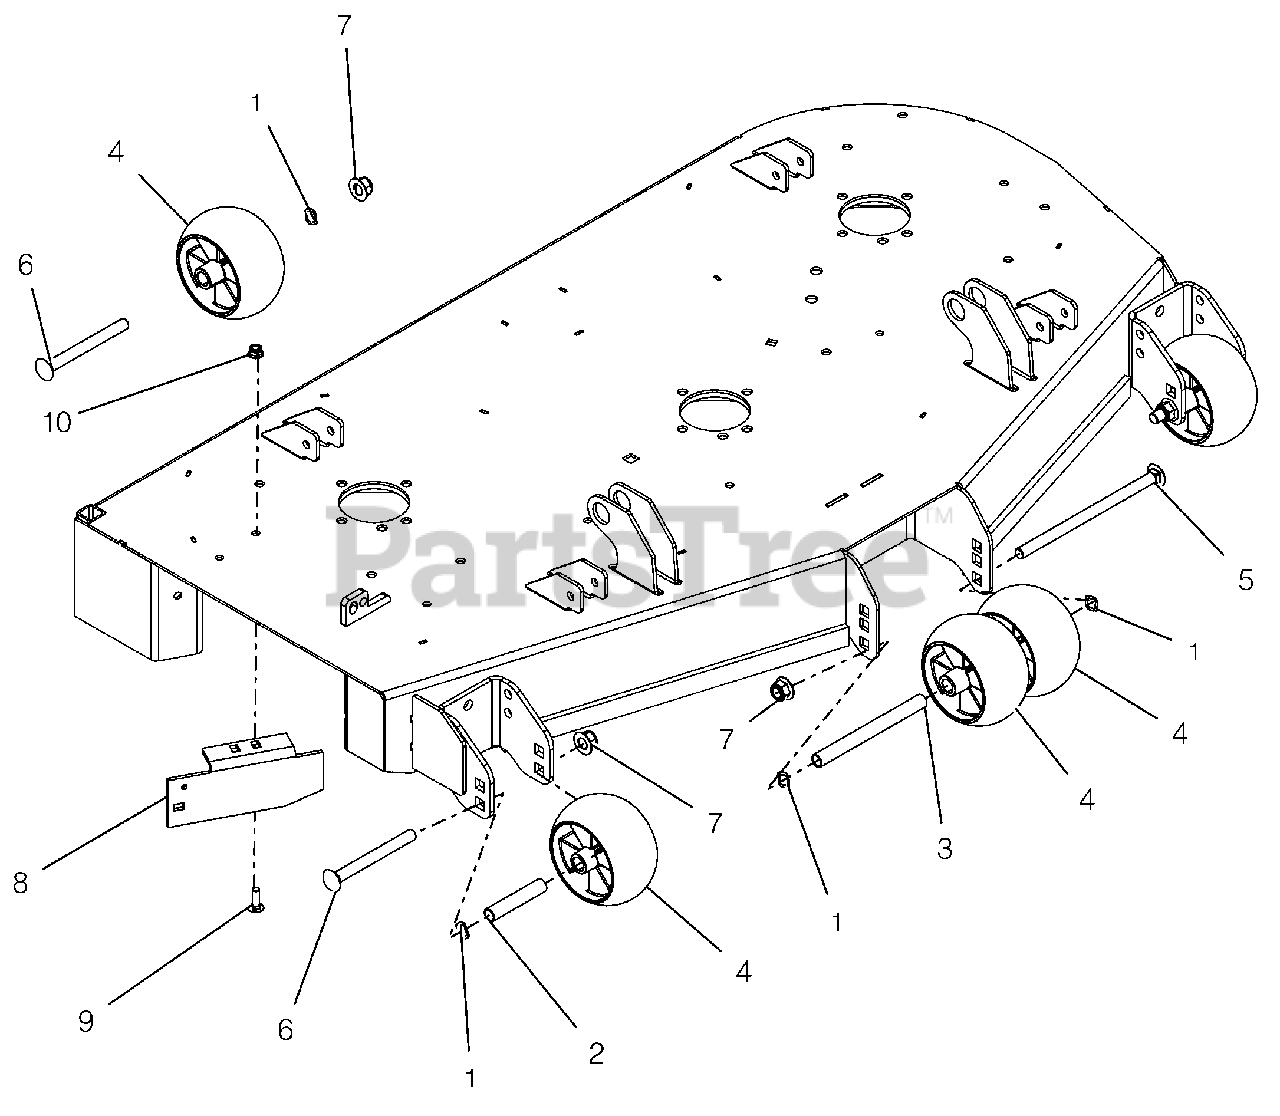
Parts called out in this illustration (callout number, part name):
1	WAVE WASHER .531X.781X.125FH
2	SPACER, .510X.625X3.35
3	SPACER, .510X.625X6.50
4	ANTI-SCALP WHEEL - 5X3 CTR
5	@BLT-RDHDSQNK .50-13X8.50 G5YZ
6	BLT-RDHDSQNK .50-13X5.00 GR5YZ
7	@NUT-LK-NYL-FLG .50-13 YWZC
8	44"-48" SIDE DISCH BAFFLE -RED
9	@BLT-RDHDSQNK .31-18X1.00 G5YZ
10	@NUT-LK-NYL-FLG .31-18 YWZC
